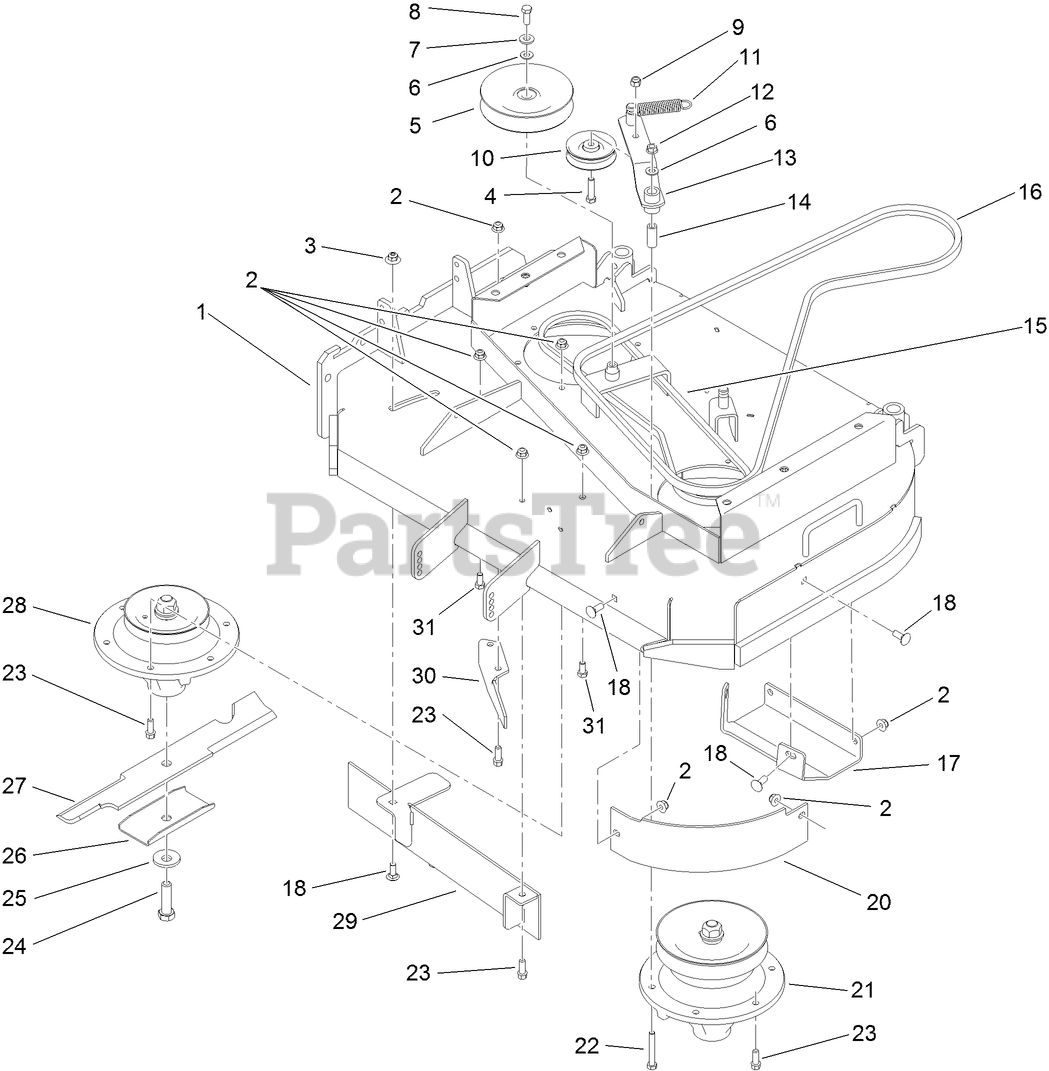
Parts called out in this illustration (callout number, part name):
1	DECK ASM
2	NUT-HF, NI
3	NUT-FLANGE, NI
4	SCREW-HH
5	PULLEY-IDLER
6	WASHER-FLAT
7	WASHER-BELLEVILLE
8	SCREW-HH
9	NUT-LOCK, NI
10	PULLEY-IDLER
11	SPRING-EXTENSION
12	NUT-HF
13	IDLER ARM ASM
14	SLEEVE-PIVOT, IDLER
15	BELT-V
16	BELT-V
17	PLATE-SKID
18	BOLT-CARR
20	BAFFLE-FRONT, LH
21	SPINDLE ASM
22	SCREW-HH
23	SCREW-HWH
24	SCREW-BLADE
25	Washer-Blade Bolt, Heavy
26	STIFFENER-BLADE
27	BLADE-18IN, HI FLOW
28	SPINDLE ASM
30	BAFFLE-DISCHARGE
31	SCREW-HH
